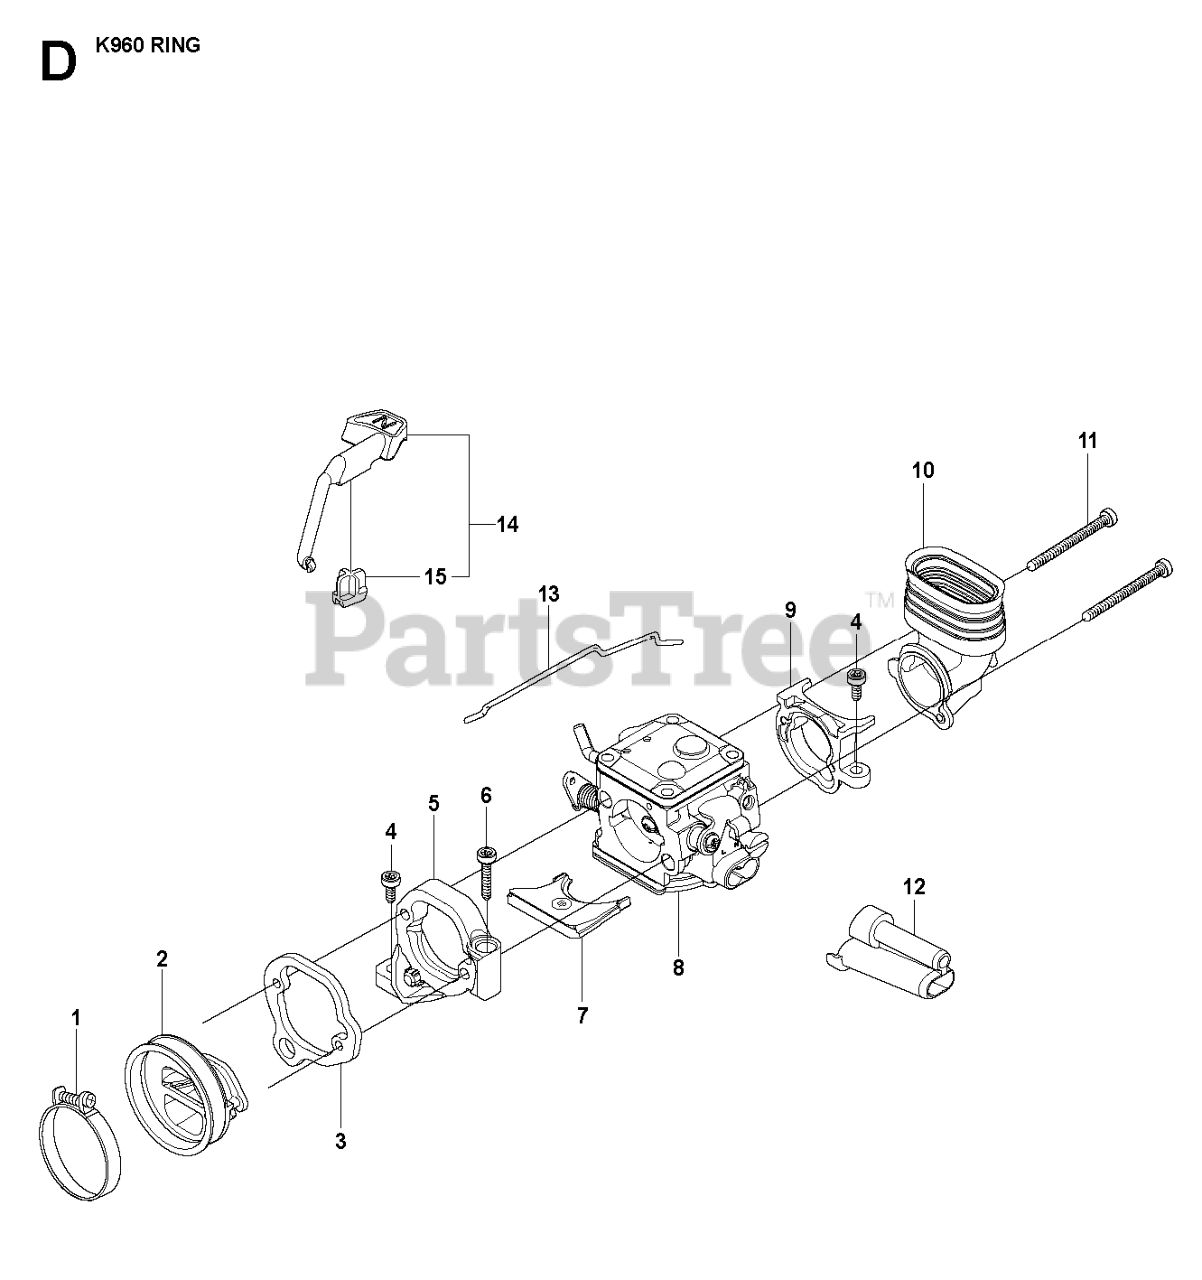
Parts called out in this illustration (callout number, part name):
1	RP HOSE CLAMP
2	INLET PIPE
8	CARBURETOR ASSY RWJ-3
10	INLET BEND
11	SCREW
12	CHISEL GUIDE
13	THROTTLE ROD
14	CHOKE CONTROL
